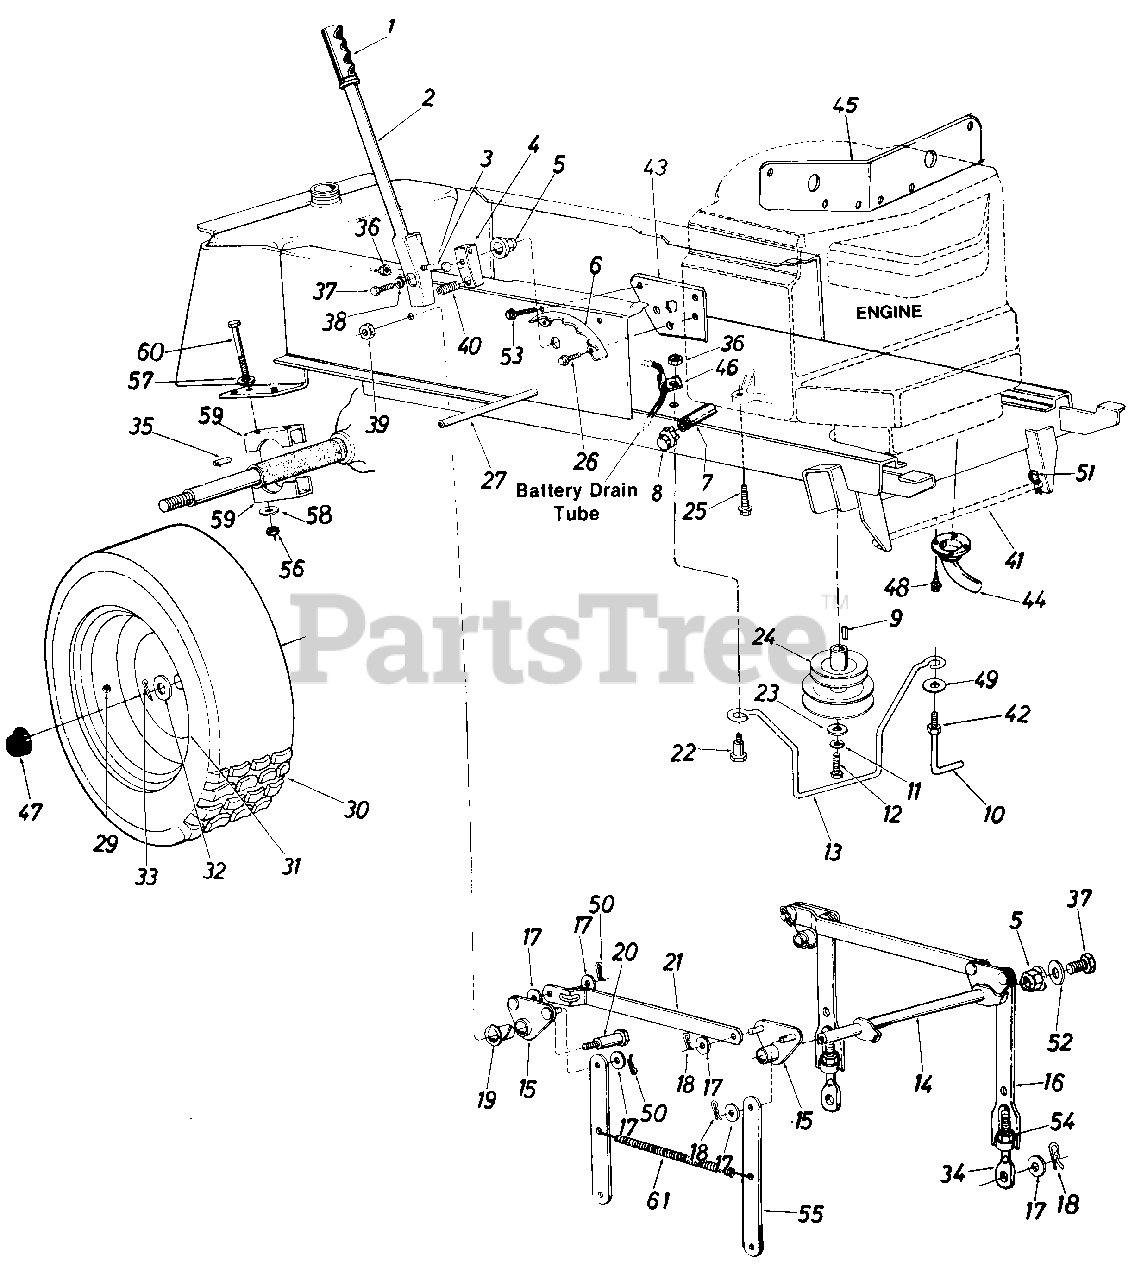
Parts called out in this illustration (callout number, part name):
2	Lift Handle Ass'y.
3	Hex Scr. 5/16-18 x 1.50" Lg.*
4	Lift Shaft Drive
5	Plastic Hex Brg. 5/8" I.D.
6	Index Brkt. Deck Lift
7	Pipe Nipple 3/8-18 Npt.
8	Pipe Cap 3/8-18 Npt.
9	Sq. Key 1/4" x 1/4" x 1.50" Lg.
10	Belt Guard Lock Pin
11	L-Wash. 7/16" Scr.*
12	Hex Scr. 7/16-20 x 1.50" Lg.
13	Belt Guard
14	Lift Shaft Ass'y.
15	Lift Pivot Brkt. Ass'y.
16	Adj. Deck Lift Link
17	Fl-Wash. 1/2" I.D. x 1.00" O.D. x .090
18	Hairpin Cotter
19	Nyliner 5/8" I.D. x .88" Lg.
20	Shld. Scr. 5/8" Dia. x .96" Lg. 3/8-16
21	Connecting Link
22	Shld. Scr. .437 Dia. x .268 Lg. 5/16-18
23	Flat Wash. .44" I.D. x 1.25" O.D. x .17
24	Two-Step Engine Pulley 4.75' & 5.56
25	Hex Wash. Hd. Scr. 3/8-16 x 1.25" Lg.
26	Hex Thd. Rolling Scr. 5/16-24 x .75" Lg.
27	Running Board Rod
27	Spacer 1.0" I.D. x 1.25" O.D. x 2.12" Lg.
29	Air Valve
33	Cotter Pin 3/16" Dia. x 1.50" Lg.
34	Eye Bolt Adj. Link 1/2-13 Thd.
35	Sq. Key 1/4 x 3.0"
36	Hex Cent. L-Nut 5/16-18 Thd.
37	Hex Scr. 5/16-24 x .62" Lg.*
38	L-Wash. 5/16" Scr.*
39	Hex Top L-Nut 3/8-16 Thd.
40	Compression Spring
41	Deck Connecting Rod
42	Hex Nut 5/16-24 Thd.*
43	Index Brkt. Reinforcement Plate
44	Exhaust Pipe
45	Heat Shield
46	Mounting Clamp
47	Hub Cap
48	Hex Wash. Hd. AB-Tap Scr. #10 x .50" Lg.
49	Belle-Wash. .39" l.D.
50	Cotter Pin .09 Dia. x 1.0" Lg.
51	Int. Cotter Pin
52	Flat Wash. .34" I.D. x 1.12" O.D. x .125
53	Hex Wash. Hd. AB-Tap Scr. 5/16 x .50" Lg.
54	Hex Nut 1/z-13 Thd.
55	Deck Link
56	Hex Nut 3/8-16 Thd.*
57	Fl-Wash. .385" I.D. x .87" O.D.
58	Bell-Wash. .39" I.D. x 1.13" O.D.
59	Rear Axle Bracket
60	Hex Bolt 3/8-16 x 3.5" Lg.
61	Extension Spring 8.25" Lg.
